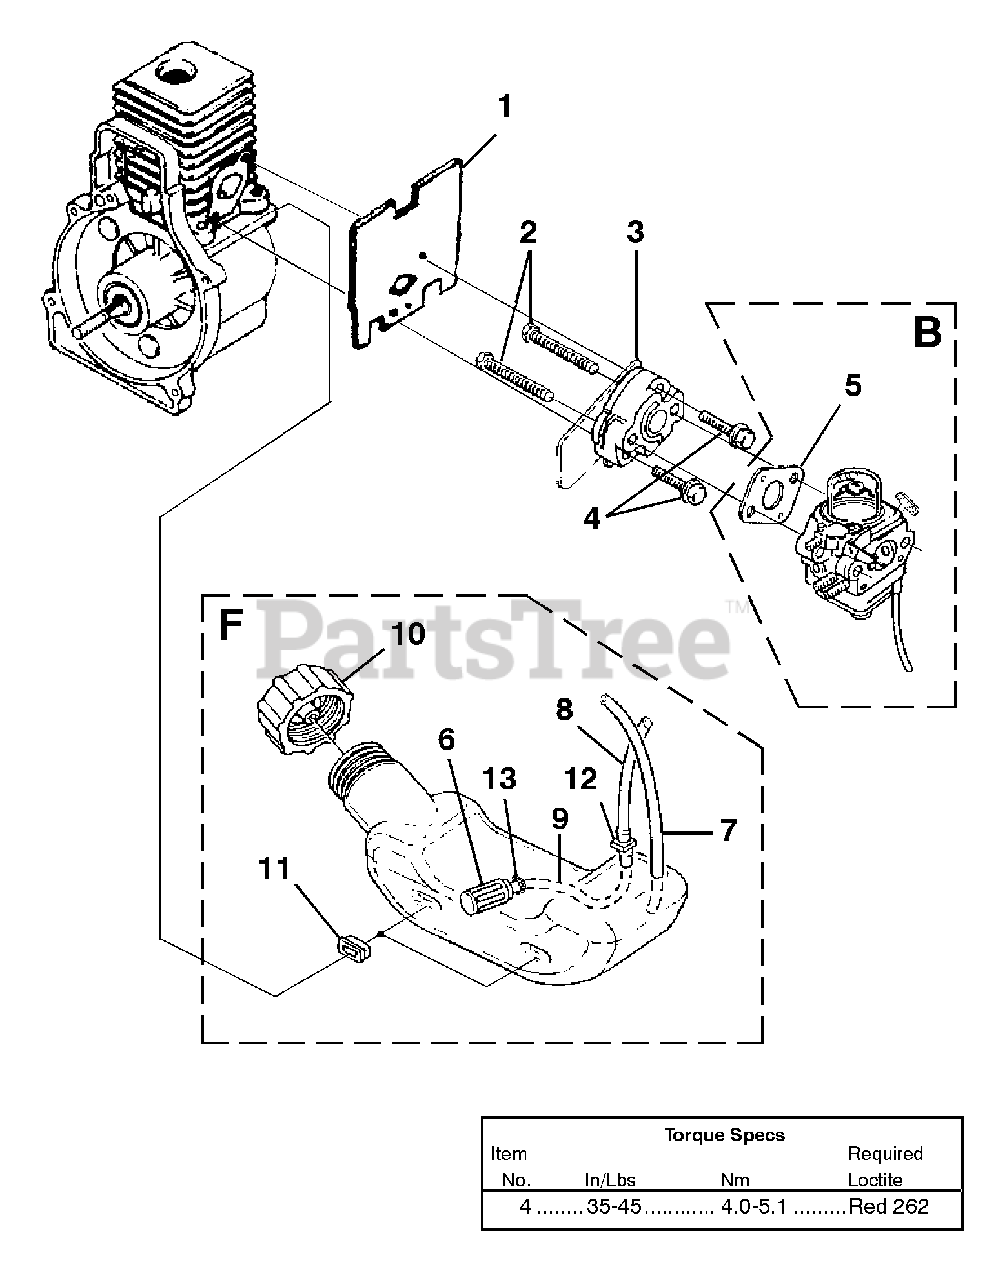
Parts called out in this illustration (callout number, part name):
1	GASKET-Heat Dam
2	SCREW-Machine (10-24 X 2 1/4")
3	HEAT DAM
4	SCREW-Sems (10-24 X 1")
5	GASKET-Carburetor
6	FILTER-Fuel
7	TUBING-Rubber
8	TUBING-Rubber
9	TUBING-Rubber
10	FUEL CAP
11	BUMPER-Rubber
12	FITTING-Inline
13	CLAMP
B	CARBURETOR KIT
F	FUEL TANK ASSY.
